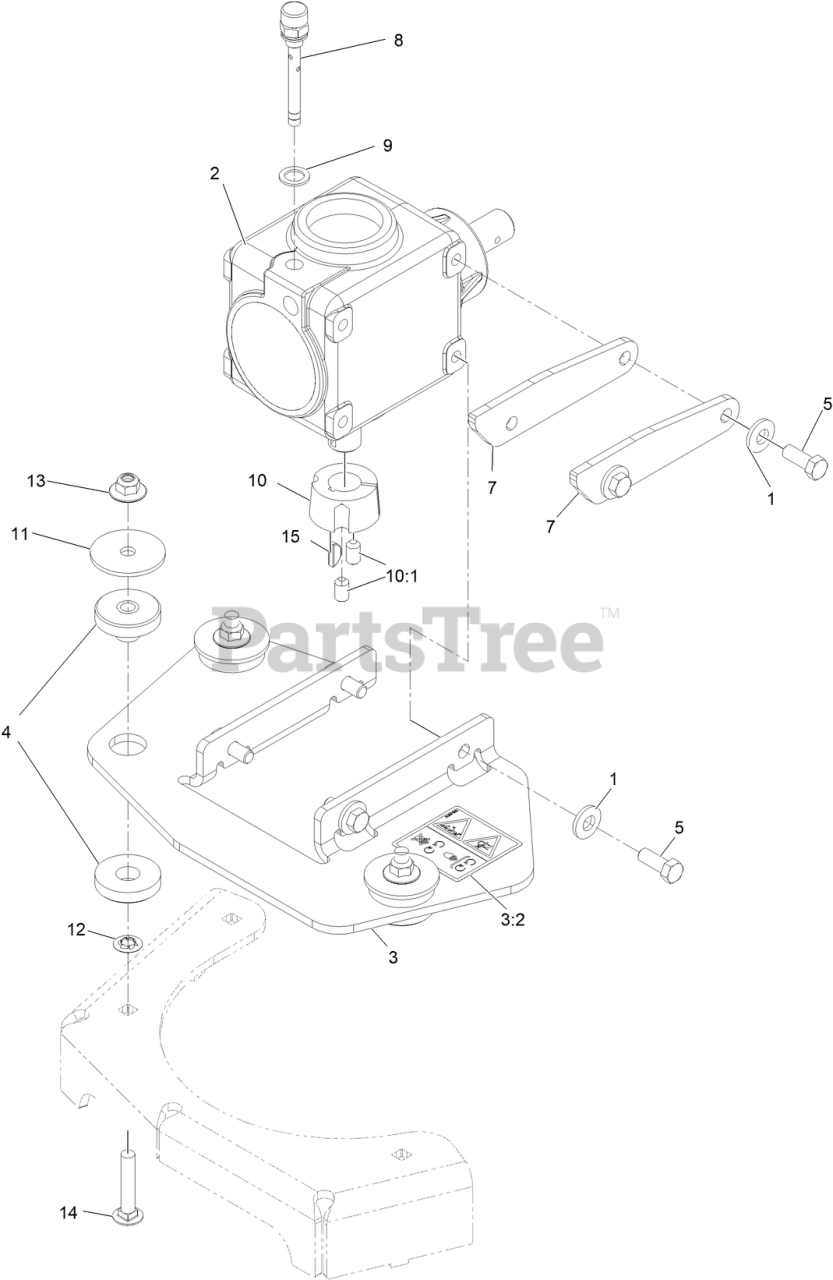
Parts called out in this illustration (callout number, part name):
1	WASHER-BELLEVILLE
2	GEARBOX ASM
3	MOUNT-GEARBOX
3:2	DECAL-HAZARD, ENTANGLEMENT
4	MOUNT-ISO
5	SCREW-HH
7	STOP-GEARBOX
8	PLUG-BREATHER
9	WASHER
10	BUSHING-TAPERLOCK
10:1	SCREW-SET
11	WASHER-FLAT
12	NUT-PUSH
13	NUT-FLANGE, NI
14	SCREW-CARR
15	KEY-WOODRUFF
